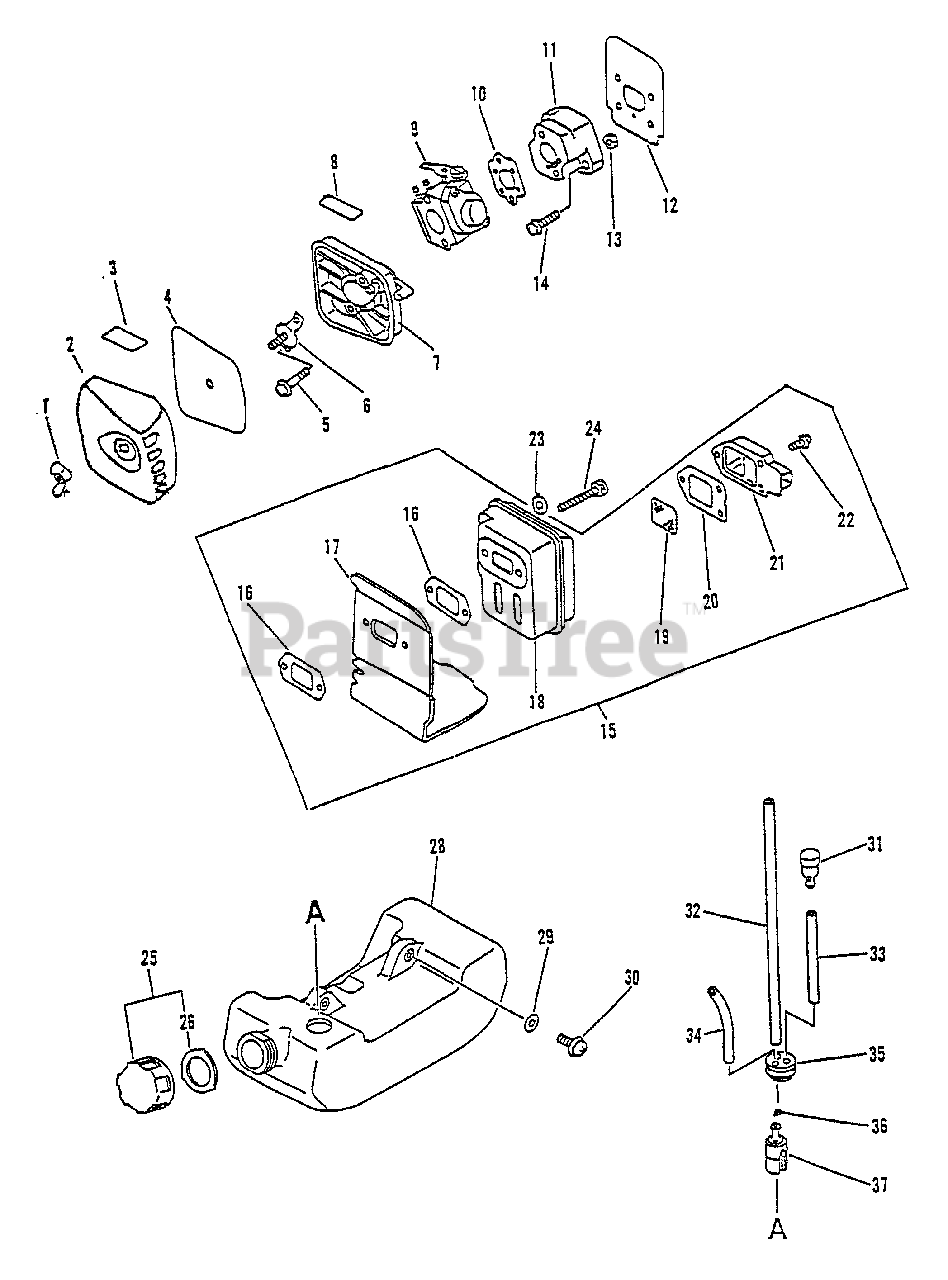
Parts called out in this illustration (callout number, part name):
1	WINGNUT - 6
2	COVER, AIR FILTER - BLACK
3	LABEL - TOP
4	FILTER, AIR
5	SCREW - 5X64
6	PLATE, PREVENT
7	AIR FILTER CASE KIT - BLACK
8	LABEL - CHOKE
9	CARBURETOR C1U-K29
10	GASKET, INTAKE
11	INSULATOR, INTAKE
12	SHIELD, INTAKE
14	SCREW - 5X20
15	MUFFLER ASSY
16	GASKET, EXHAUST
17	COVER, EXHAUST
19	SCREEN, SPARK ARRESTOR
20	GASKET, EXHAUST
21	GUIDE, EXHAUST - OUTER
22	SCREW - 4X10
23	WASHER - 5
24	SCREW - 5X55
25	CAP ASSY
26	GASKET, CAP
28	TANK, FUEL
29	WASHER - 5
30	SCREW - 5X16
31	VENT, FUEL TANK
32	PIPE - 3X5X180 -- BLACK
33	PIPE - 3X5X70 -- BLACK
34	PIPE - 3X6X80 -- CLEAR
35	GROMMET
36	CLIP - 6
37	FILTER, FUEL
